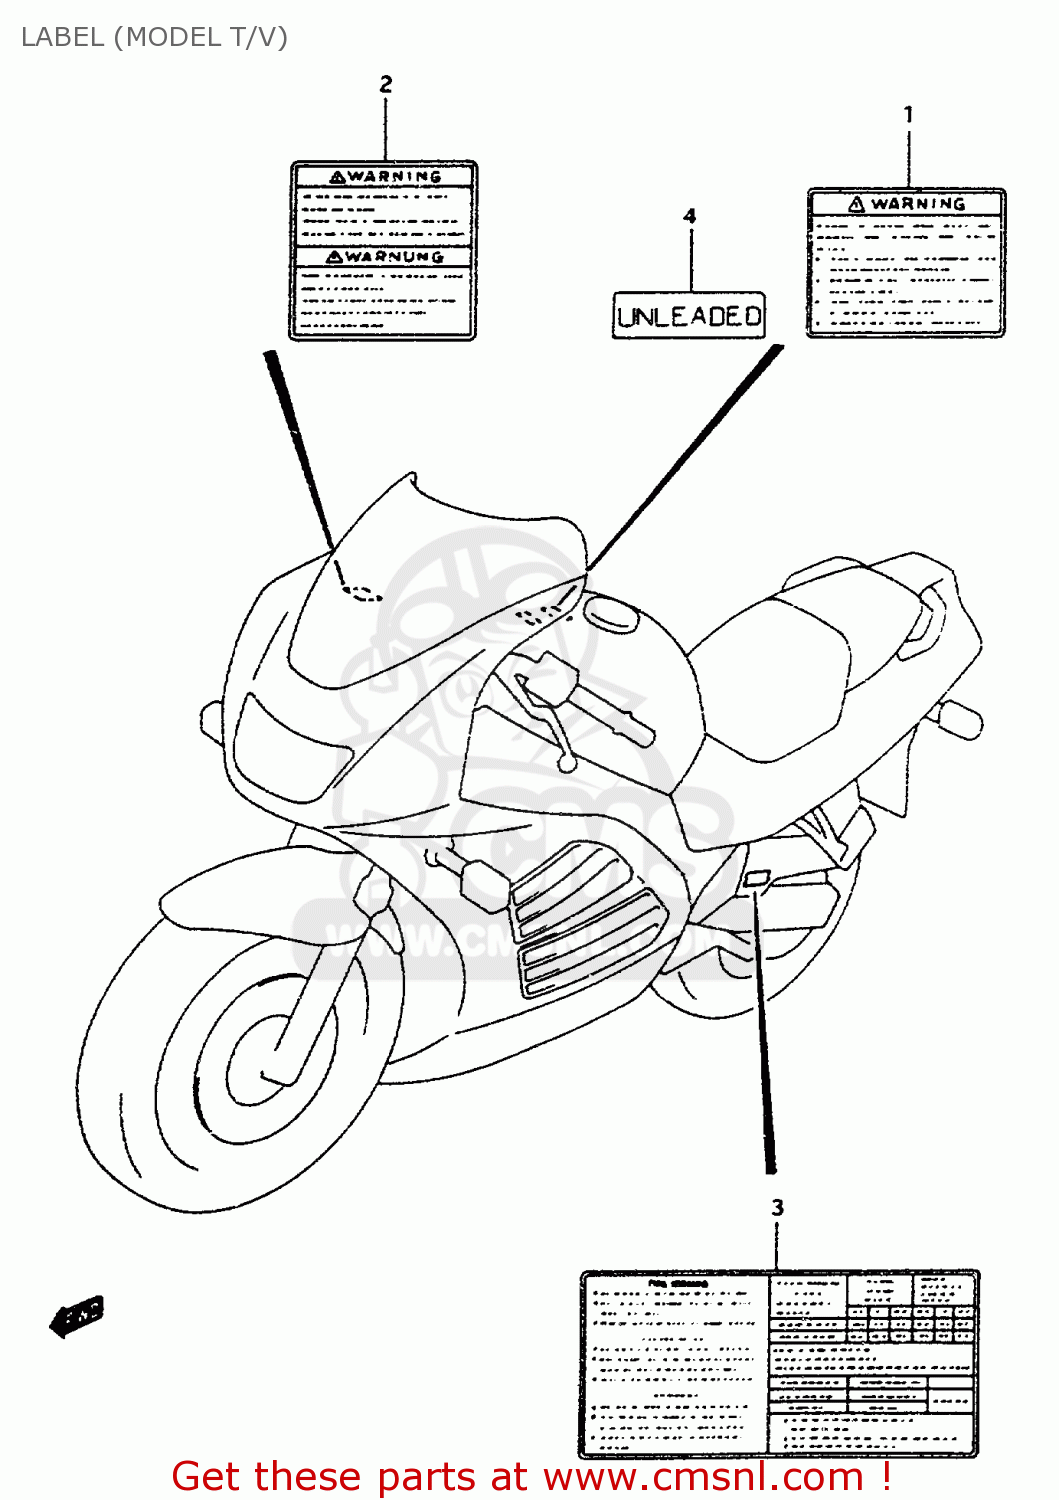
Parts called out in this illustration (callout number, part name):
1	LABEL,WARNING
2	LABEL,WARNING STEERING
3	LABEL,TIRE AIR
4	LABEL,CAUTION
5	MANUAL,OWNER'S
